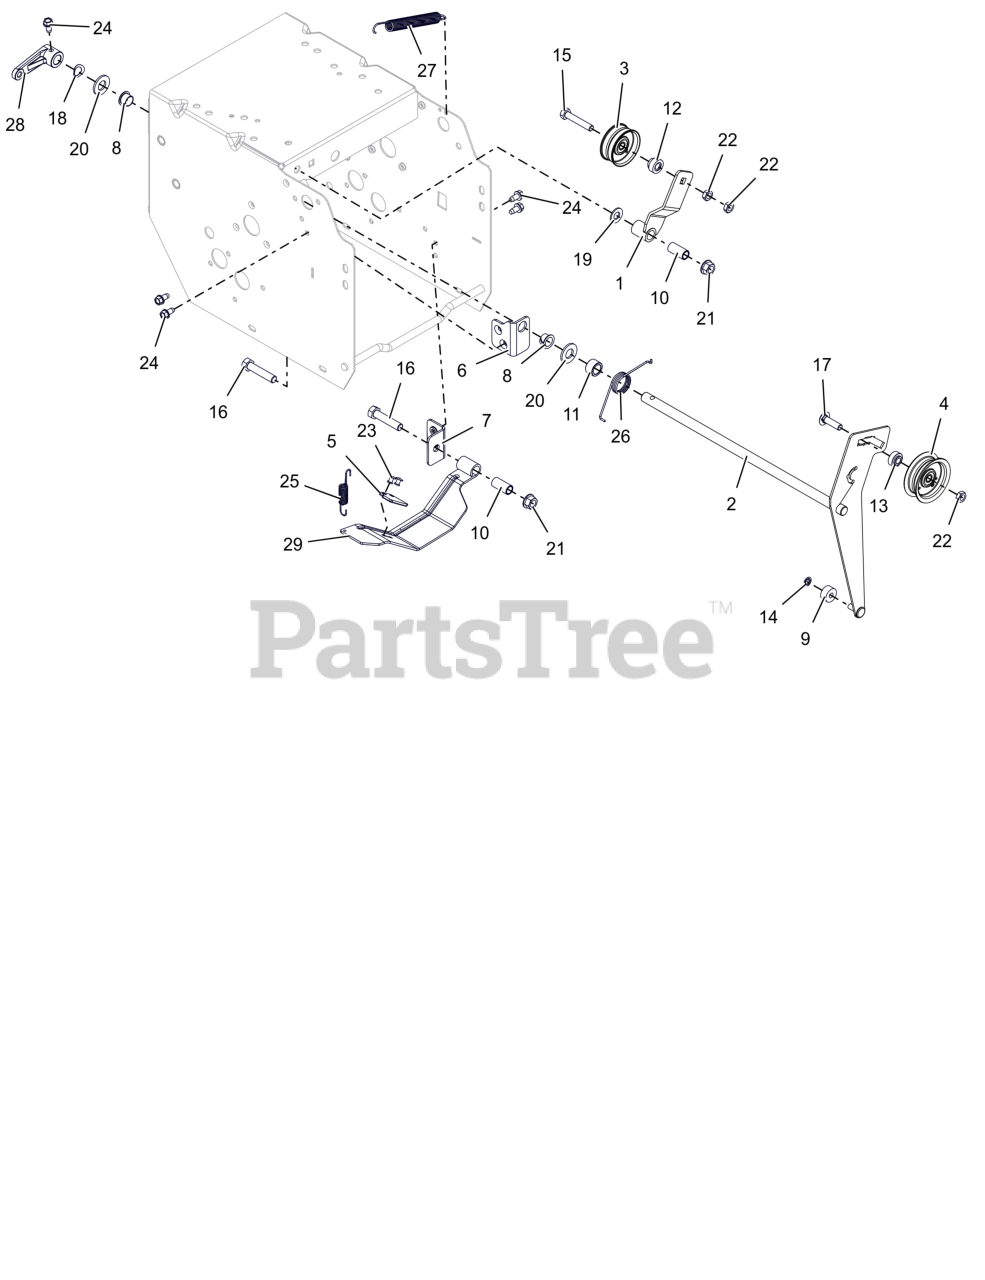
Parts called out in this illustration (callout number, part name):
1	WELDMENT, TRACTION IDLER ARM
2	WELDMENT- ATTACHMENT IDLER ARM
3	IDLER, FLAT - 1.875"
4	IDLER, FLAT - 2.00"
5	PAD, BRAKE
6	BRACKET, MOUNT - IDLER ARM
7	BRACKET, MOUNT - BRAKE
8	BUSHING, POLYLINER-.50 SPLIT
9	BSHG,SLV .265 X .625 X .375
10	BSHG-SLV .385X.500X1.045
11	BSHG-SLV .510X.751X.475
12	SPCR, BRG .315X.500X.481X.281
13	SPCR, BRG .315X.500X.358X.281
14	RG-RTNG-EXT .250X.010
15	BLT, HEX .31-18X1.75 G5 ZCC
16	BLT, HEX .38-16X1.75 G5 ZCC
17	BLT, RHSSN .31-18X1.125 G5 ZCC
18	WSHR-WAVE .50X.75X.015 .13FRHT
19	WSHR,FLT .406X.812X.065 ZCC
20	WSHR,FLT .531X1.062X.095 ZCC
21	NUT-LK-TOP-FLG .38-16 ZC120
22	NUT-LK-CTR-JAM .312-18 GB ZCC
23	RVT, POP .1875 ZCC
24	SCR-TAP .25-20X.50 HWH ZCC
25	SPRING-EXT .437 X .438 X 2.64
26	SG-TORS .075 X .955
27	SPRING, EXTENSION
28	ARM CLUTCH - ATTACHMENT
29	BRAKE ARM W/PAD
